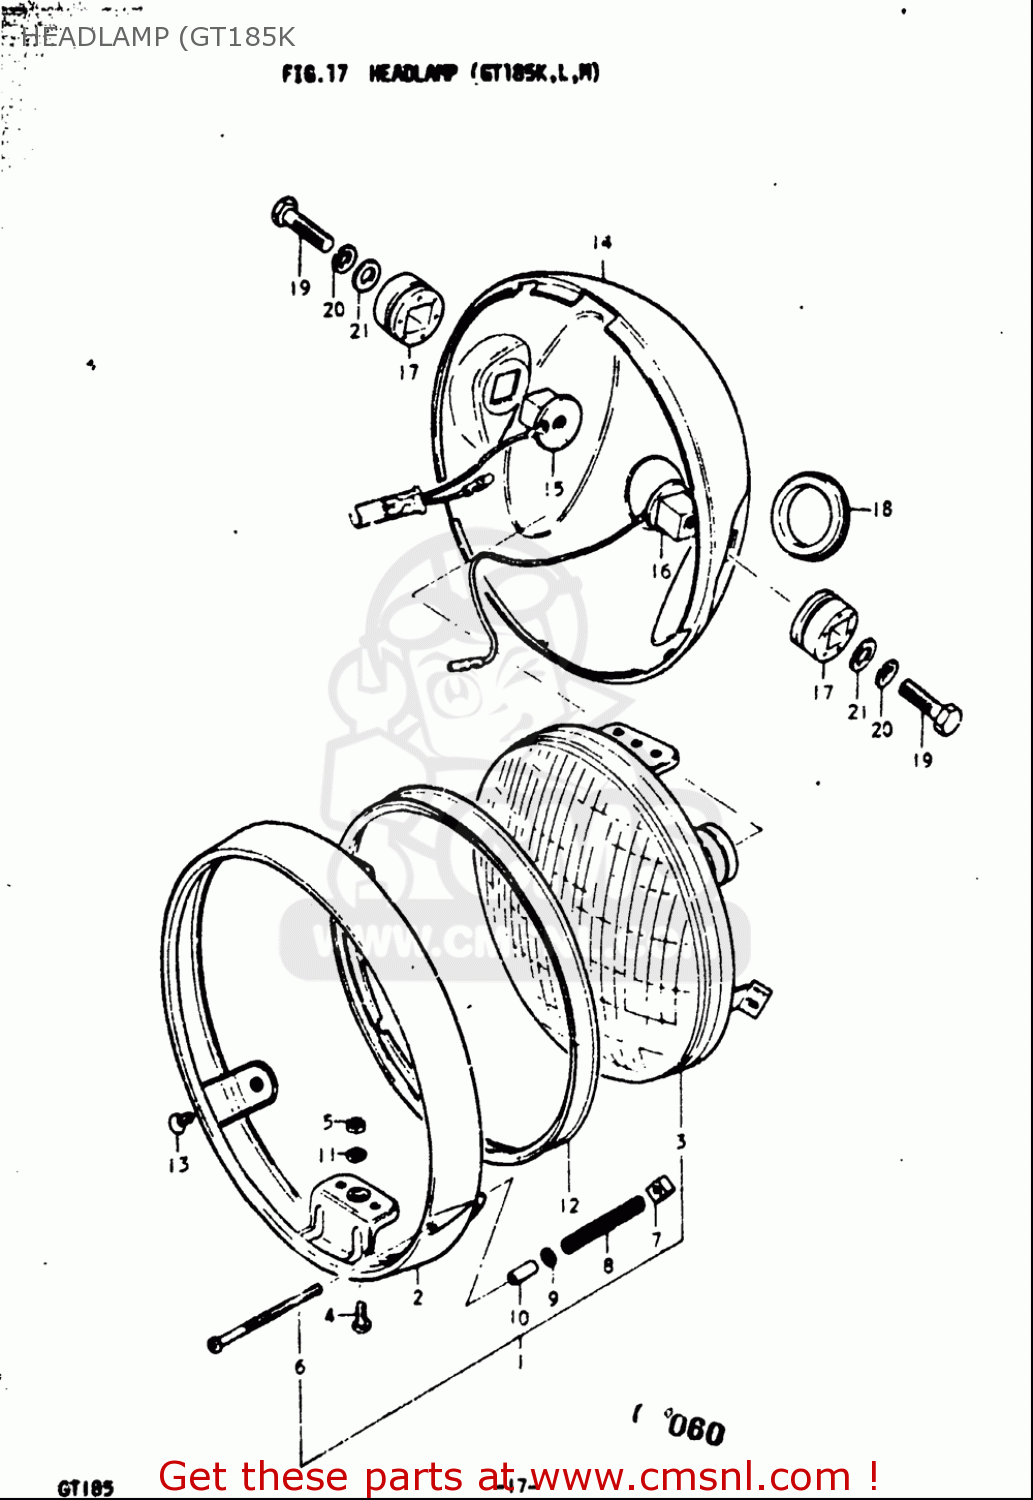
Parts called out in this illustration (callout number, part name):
4	H/LAMP LENS UNIT FITING SCRE
5	NUT
6	SCREW
7	NUT
9	WASHER
11	WASHER,LOCK
12	RETAINER,HEADLAMP
13	SCREW
14	HOUSING,HEADLAMP
15	CUSHION,HEADLAMP HOUSING
17	CUSHION,HEADLAMP HOUSING
18	GROMMET,HEADLAMP HOUSING
19	BOLT
20	WASHER,LOCK
21	WASHER
